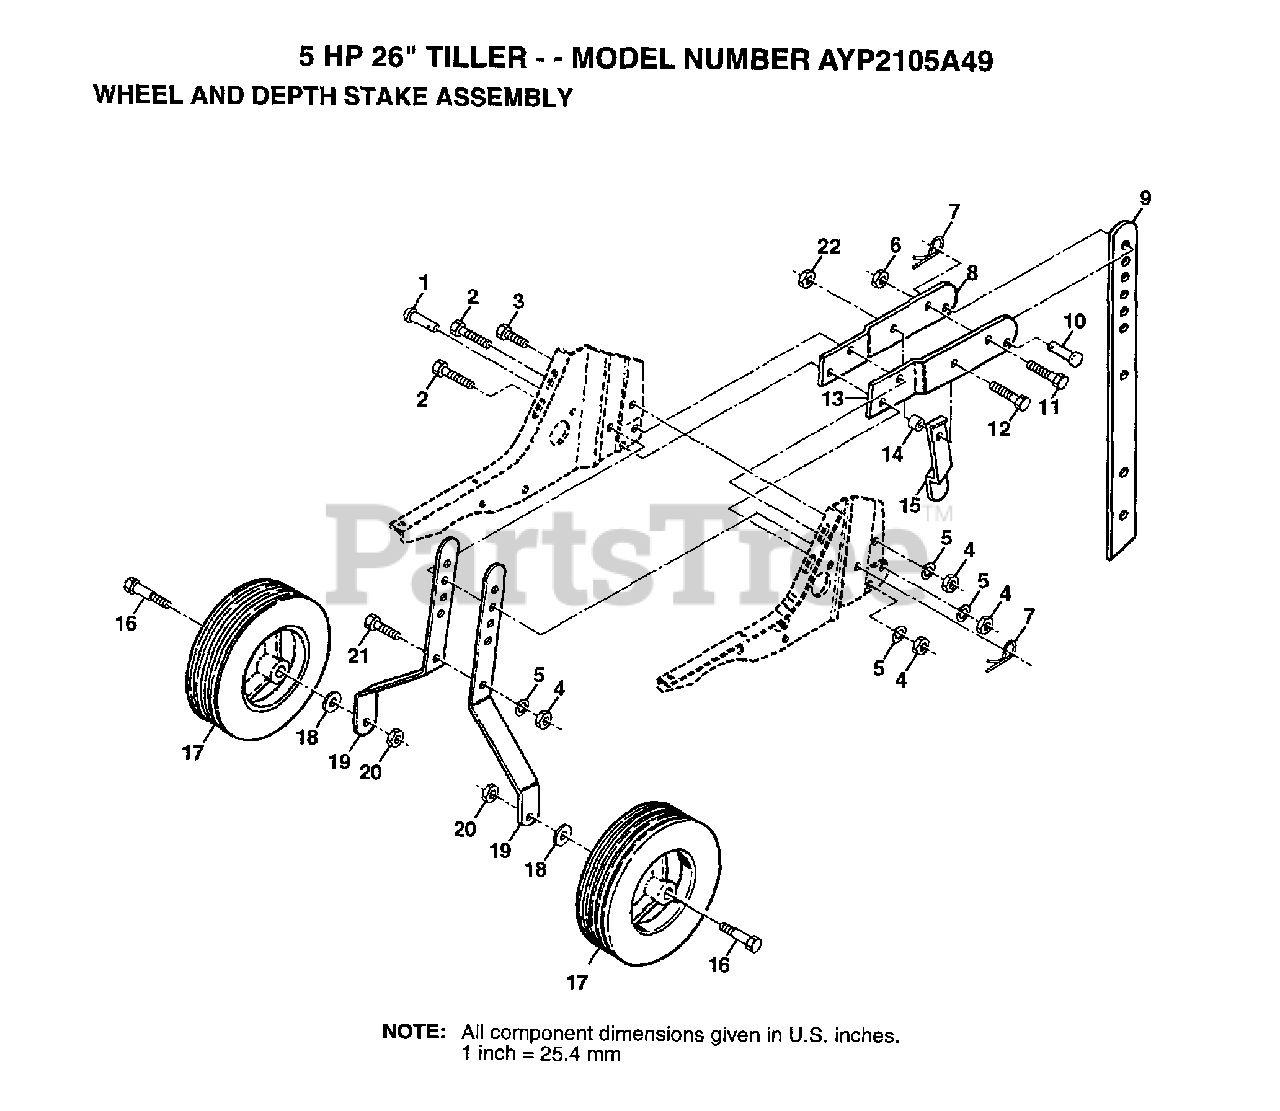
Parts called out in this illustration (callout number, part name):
1	DRILLED RIVET RT
3	BOLT
4	NUT.HEX.5/16-18
5	LOCKWASHER
6	NUT
7	SPRING.RETAINER
8	SUPPORT STAKE RH
11	BOLT
12	BOLT.HEX.5/16-1.5
13	SUPPORT STAKE LH
14	WASHER
15	STAKE SPRING TI
16	BOLT SHOULDER
18	WASHER
19	BRACKET.WHL.PNT.
22	NUT
